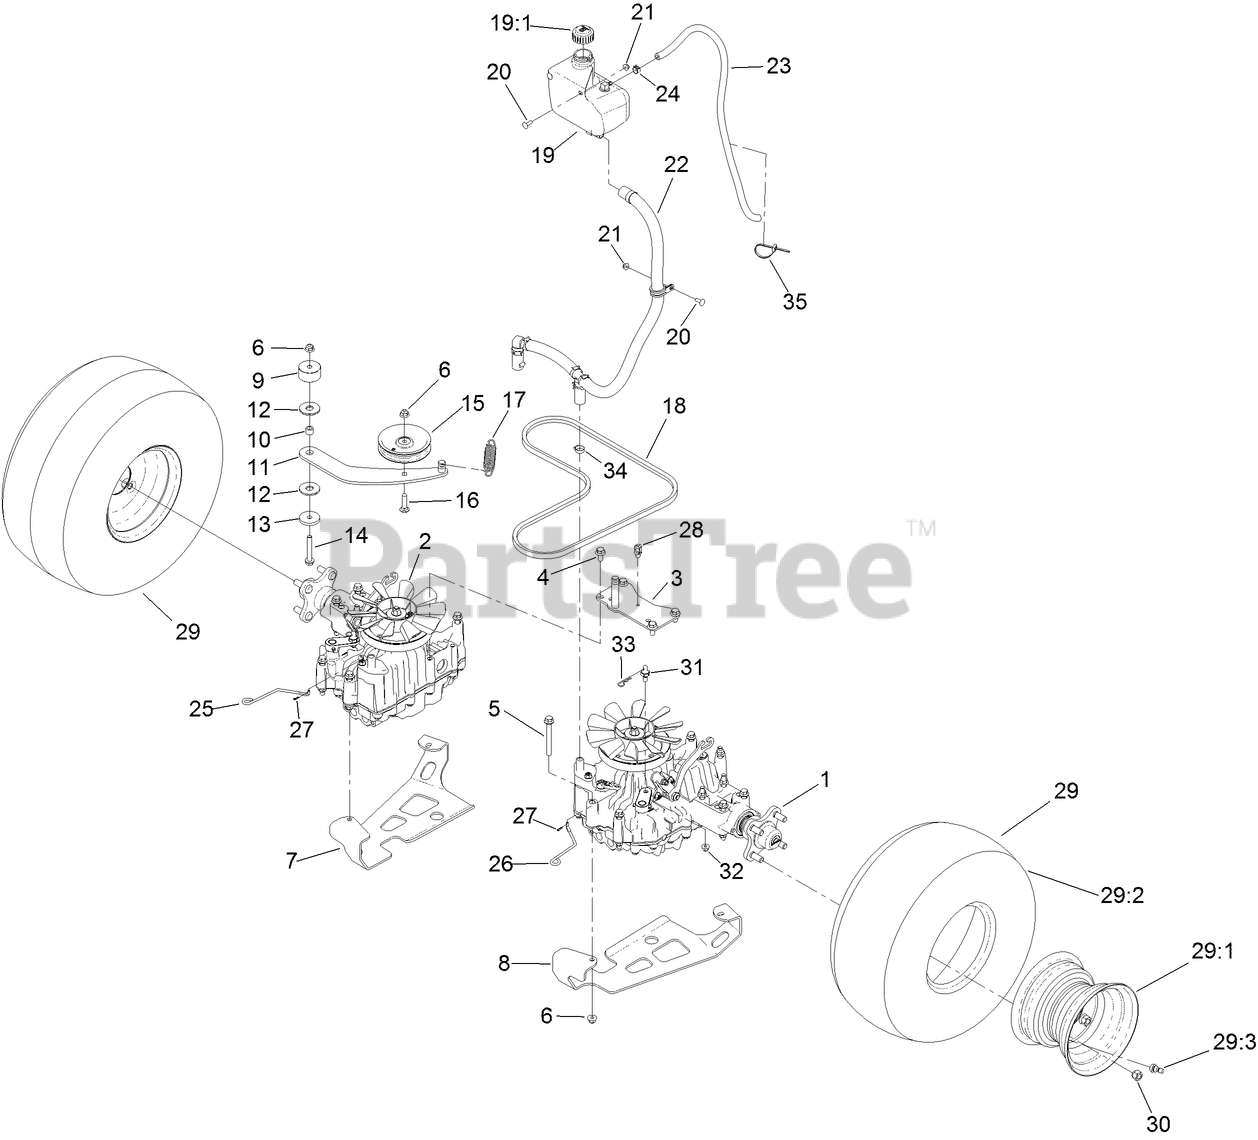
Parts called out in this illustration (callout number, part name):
1	LH TRANSMISSION ASM
2	RH TRANSMISSION ASM
3	SUPPORT-TRANSAXLE
4	SCREW-HHF
5	SCREW-HHF
6	NUT-HF, NI
7	PLATE-SKID, TRANSMISSION (RH)
8	PLATE-SKID, TRANSMISSION (LH)
9	SPACER
10	BUSHING-LEVER, LIFT
11	ARM-IDLER
12	WASHER-FRICTION, COMPOSITE
13	WASHER-PLAIN
14	SCREW-HHF
15	PULLEY-IDLER
16	SCREW-HH
17	SPRING-EXTENSION
18	BELT-V
19	TANK-HYD
19:1	CAP-VENTED
21	NUT-HF
22	HYD HOSE ASM
23	HOSE-FUEL
24	CLAMP-HOSE
25	ROD-BYPASS, RH
26	ROD-BYPASS, LH
27	PIN-HAIR
28	CLIP-TIE
29	WHEEL AND TIRE ASM
29:1	RIM-8 INCH, GRAY
29:2	TIRE
30	NUT-LUG
31	SPACER-HEX
32	NUT-HF, NI
33	PIN-COTTER
34	CLAMP-DRIVE, WORM
35	TIE-CABLE
